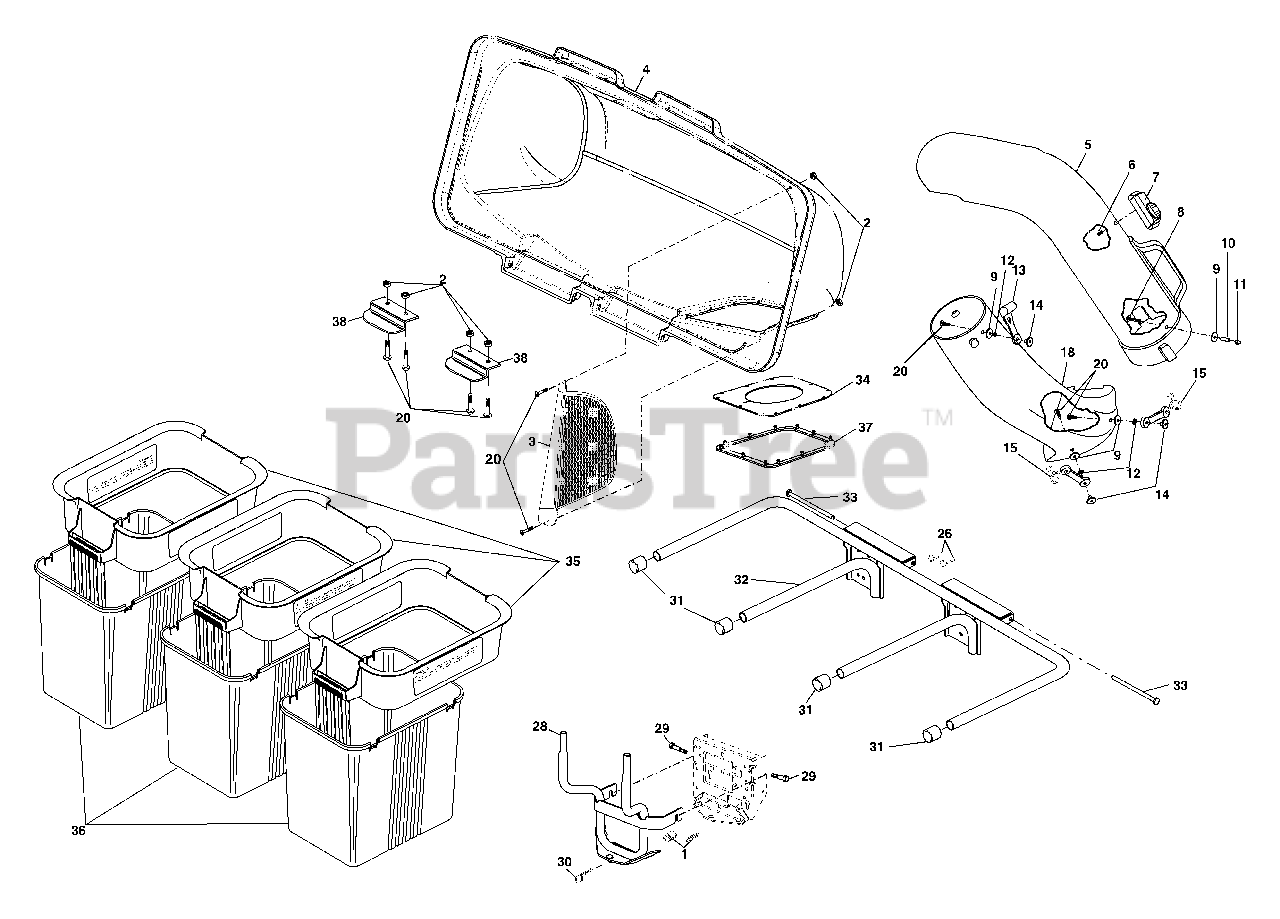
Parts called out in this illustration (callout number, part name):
2	Nut, Crownlock #10-24
3	Screen, Cover
4	Cover Assembly
5	Chute, Upper
6	Screw, Special #10-14x1/2
7	Full Bag Indicator
8	Screw, #10-24 x 1-1/8
9	Washer 3/16x3/4x16 Ga.
10	Spacer, Split
11	Nut, Acorn #10-24
12	Washer, lock
13	Latch, Chute
14	Nut, Weld
15	Latch Assembly, Hook
18	Chute, Lower
20	Screw #10-24 x 5/8
26	Spring, Retainer
28	Support Assembly
29	Shoulder Bolt,Self Tapping
30	Spring, Retainer
31	Plug, Tubing End
32	Bagger, Frame
33	Pin, Hinge
34	Gasket, Cover
35	Container, Top
36	Container, Bottom
37	Seal, Cover
38	Latch Handle, Cover
39	Strip, Reinforcement
40	Screw #10-24 x 1/2
